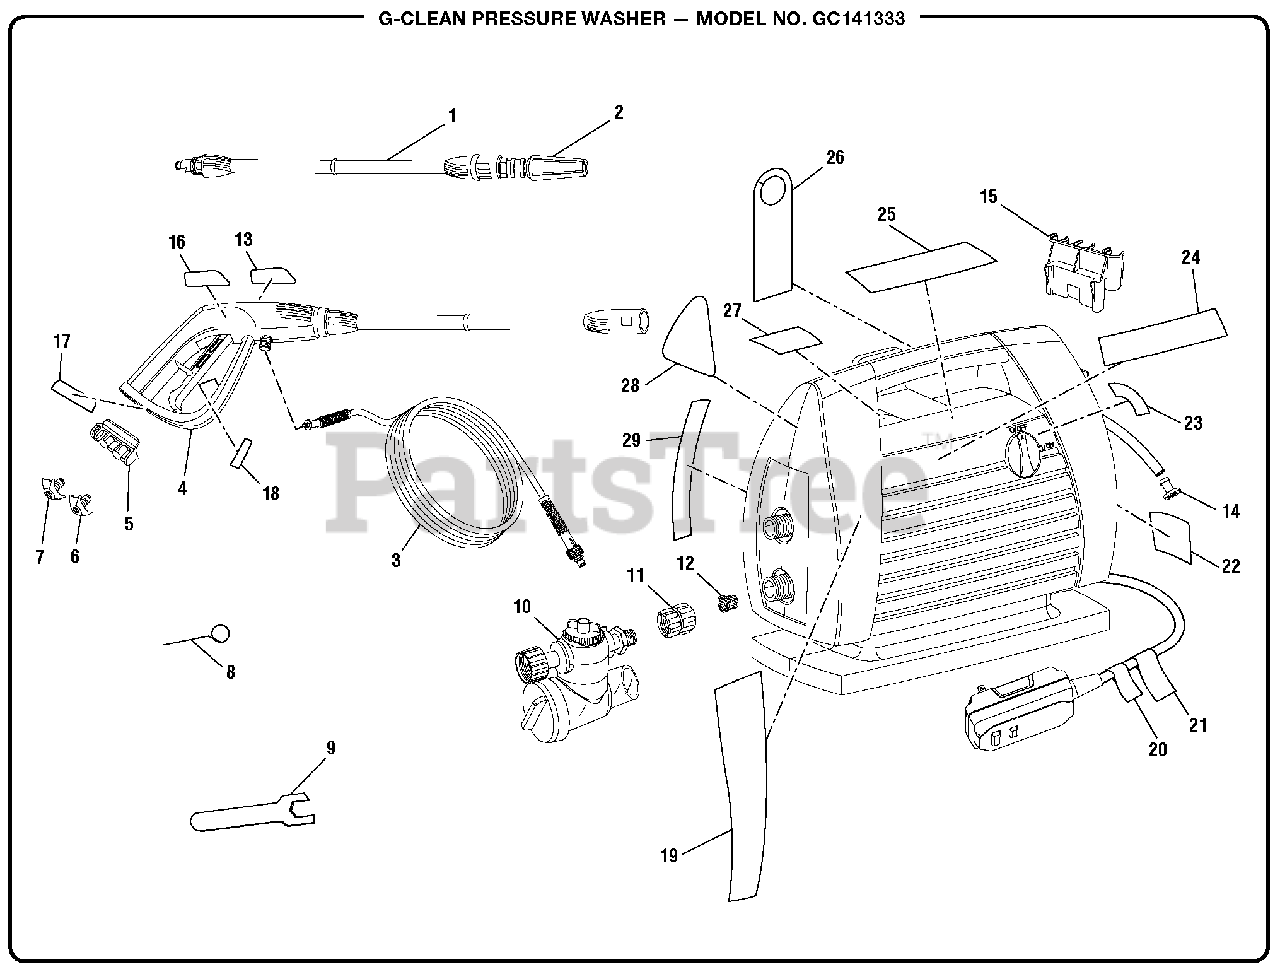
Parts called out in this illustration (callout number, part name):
1	Spray Wand
2	Turbo Nozzle
3	High Pressure Hose
4	Trigger Handle Assembly
5	Nozzle Holder
6	Soap Nozzle
7	25deg Nozzle
8	Nozzle Cleaning Tool
10	Detergent Injector
12	Water Inlet Filter
13	Trigger Handle Warning Label (English)
14	Injection Hose Filter
15	Wand Storage Bracket
16	Trigger Handle Logo Label
17	Trigger Handle Warning Label (French/Spanish)
18	Trigger Handle Rating Label
19	Large Logo Label
20	CA Proposition 65 Label
21	Cord Danger Label
22	Temperature Label
23	On/Off Label
24	Name Label
25	Danger Label
26	Danger Hang Tag
27	Data Label
28	Small Logo Label
29	Quick Start Label
